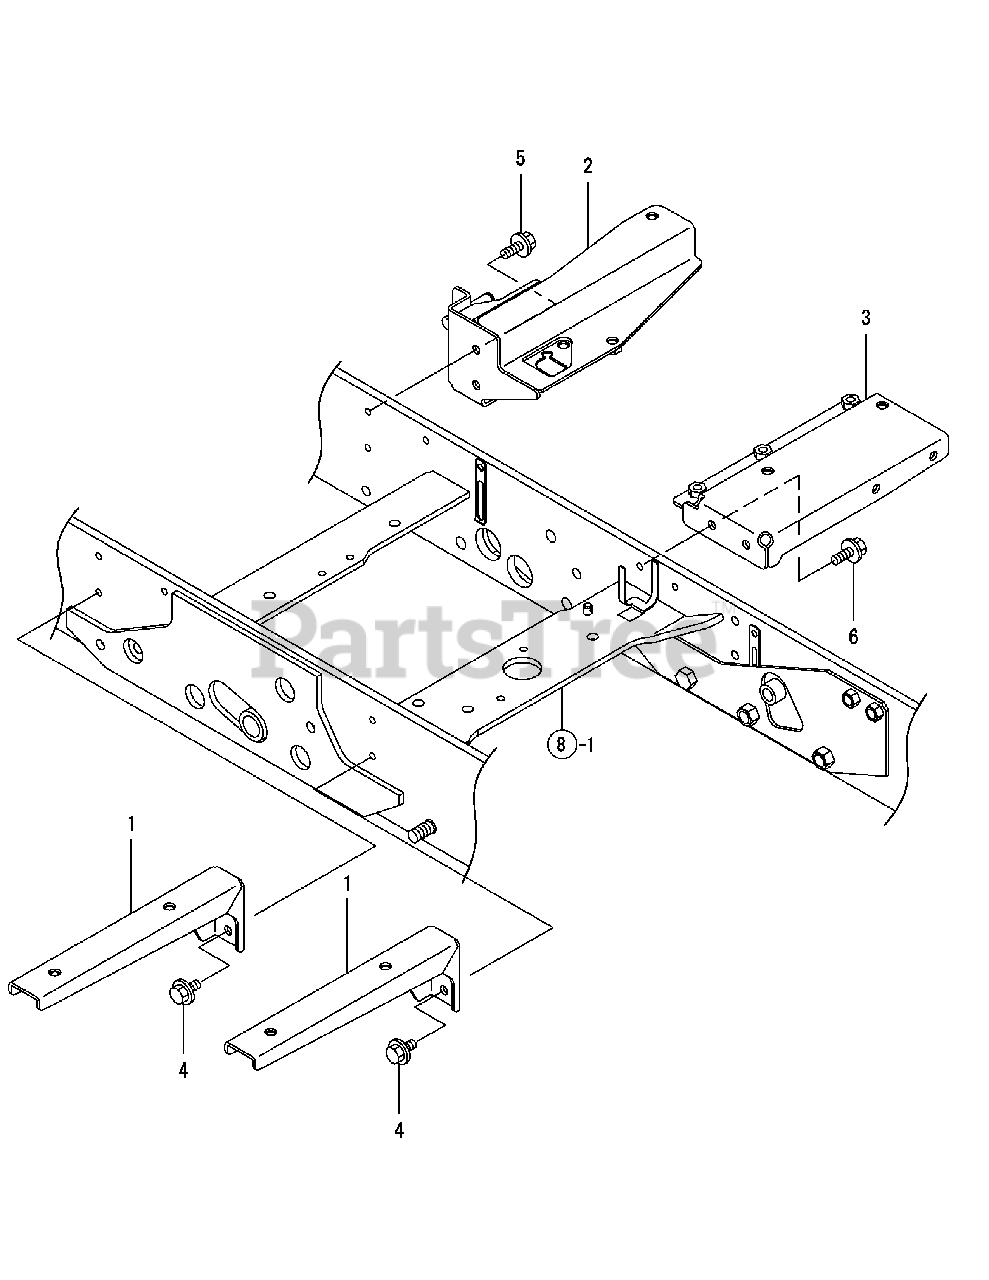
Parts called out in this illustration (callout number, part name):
1	STAY L,STEP CMP
2	STAY RF,STEP CMP
3	STAY RR,STEP CMP
4	BOLT M 8X 16 PLATED
5	BOLT M 8X 16 PLATED
6	BOLT M 8X 16 PLATED
